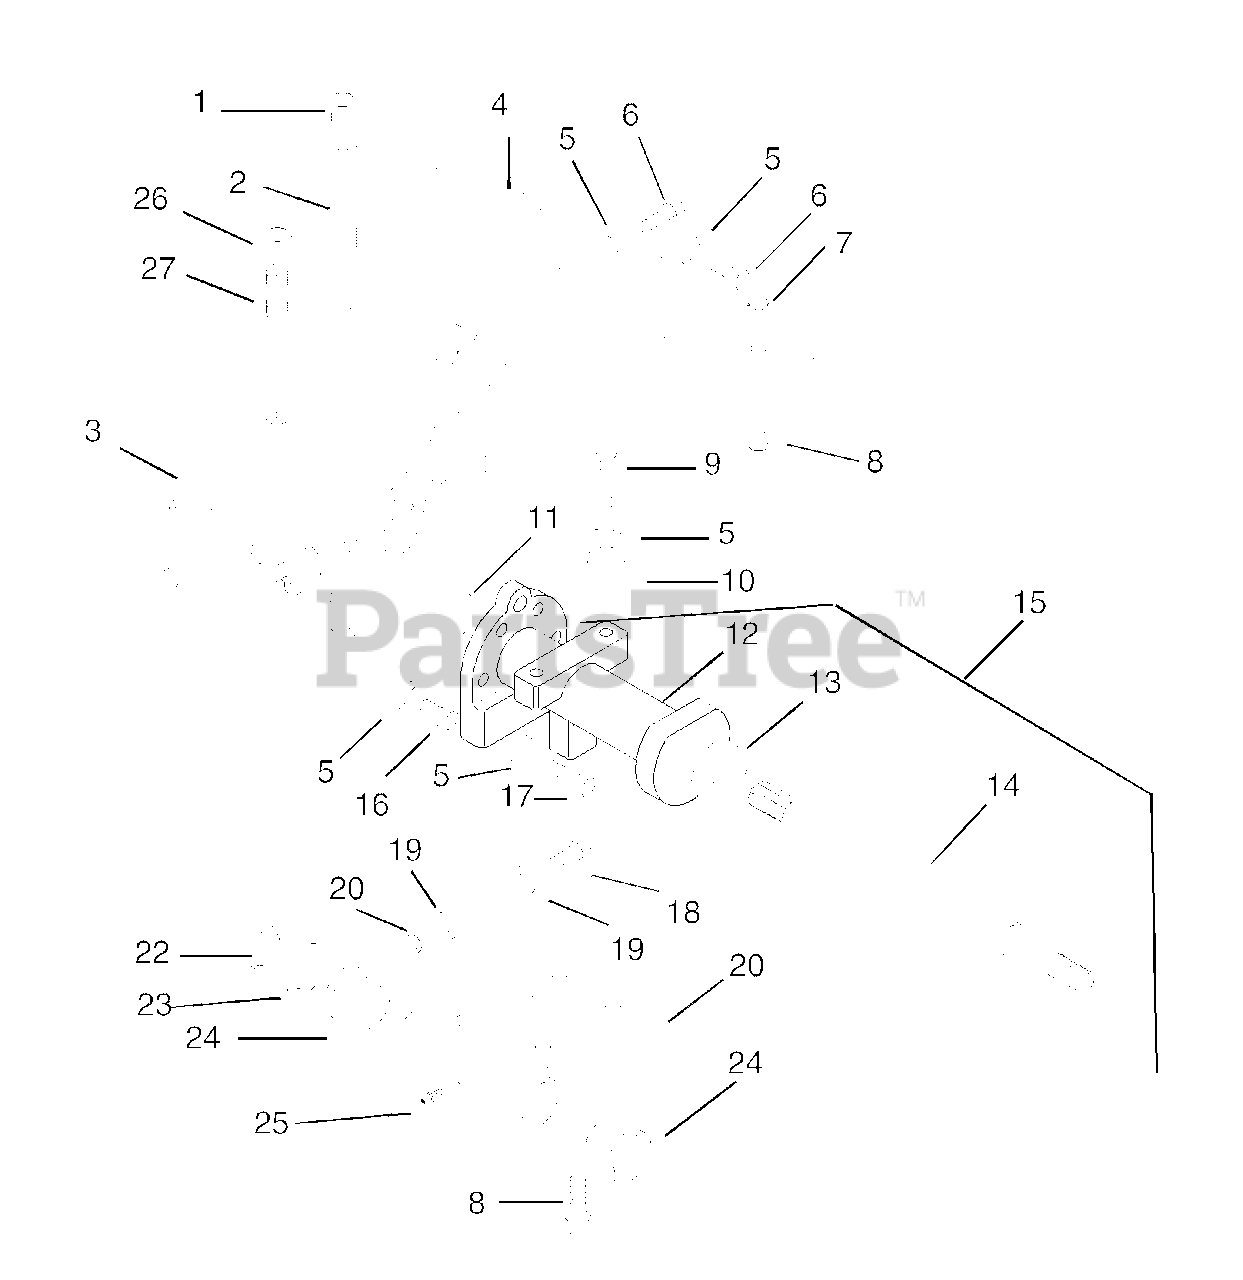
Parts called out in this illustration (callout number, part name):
1	Plug, Breather 1/2 IN NPT
2	Pipe, Reducing .75 X 5.0
3	Transaxle
4	Plate, Transaxle
5	Washer-Locking .50 X .125
6	Bolt-Hex .50-13 x 1.25 Grade 5
7	Nut-Locking-Center .62-11
8	Bolt-Hex .62-11 x 1.50
9	Bolt-Hex .50-13 x 2.75 Grade 5
10	Spacer, Frame
11	Ring, Alignment
12	Housing, Axle
13	Bearing, Ball 1.181 x 2.440 x .629
14	Axle, w/Taper
15	Assembly, Axle Housing
16	Bolt-Hex .50-13 x 1.50 Grade 5
17	Bolt-Hex .50-13 x 2.25 Grade 5
18	Bolt-Hex .375-16 X 1.5 Grade 5
19	Washer-Flat-Steel .531 x 1.06 x .095
20	Weldment, Pivot Bracket
21	Nut-Locking-Center .50-13
22	Ring-Retaining-external 1.5 x 1.38
23	Washer-Thrust 1.502 x 2.18 x .063
24	Bushing-Flange 1.514 x 1.756 x 1.688 x 2.250
25	Fitting-Lube .25-28 x .256
26	Pipe Cap
